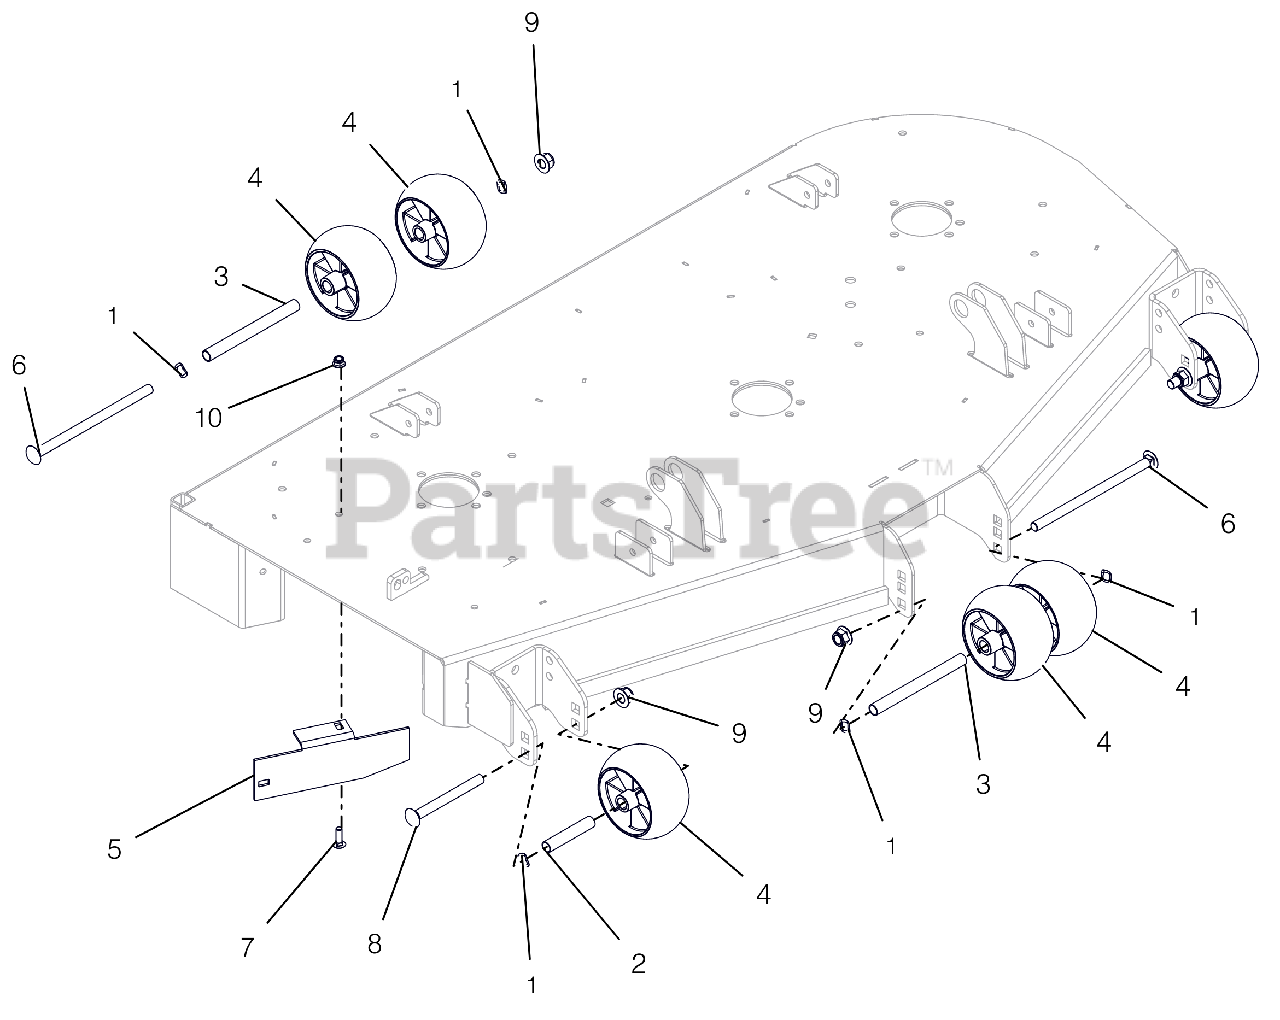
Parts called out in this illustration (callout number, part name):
1	WAVE WASHER .531X.781X.125FH
2	SPACER, .510X.625X3.35
3	SPACER, .510X.625X6.50
4	ANTI-SCALP WHEEL - 5X3 CTR
5	BAFFLE, DISCHARGE, 52"
6	@BLT-RDHDSQNK .50-13X8.50 G5YZ
7	@BLT-RDHDSQNK .31-18X1.00 G5YZ
8	BLT-RDHDSQNK .50-13X5.00 GR5YZ
9	@NUT-LK-NYL-FLG .50-13 YWZC
10	@NUT-LK-NYL-FLG .31-18 YWZC
